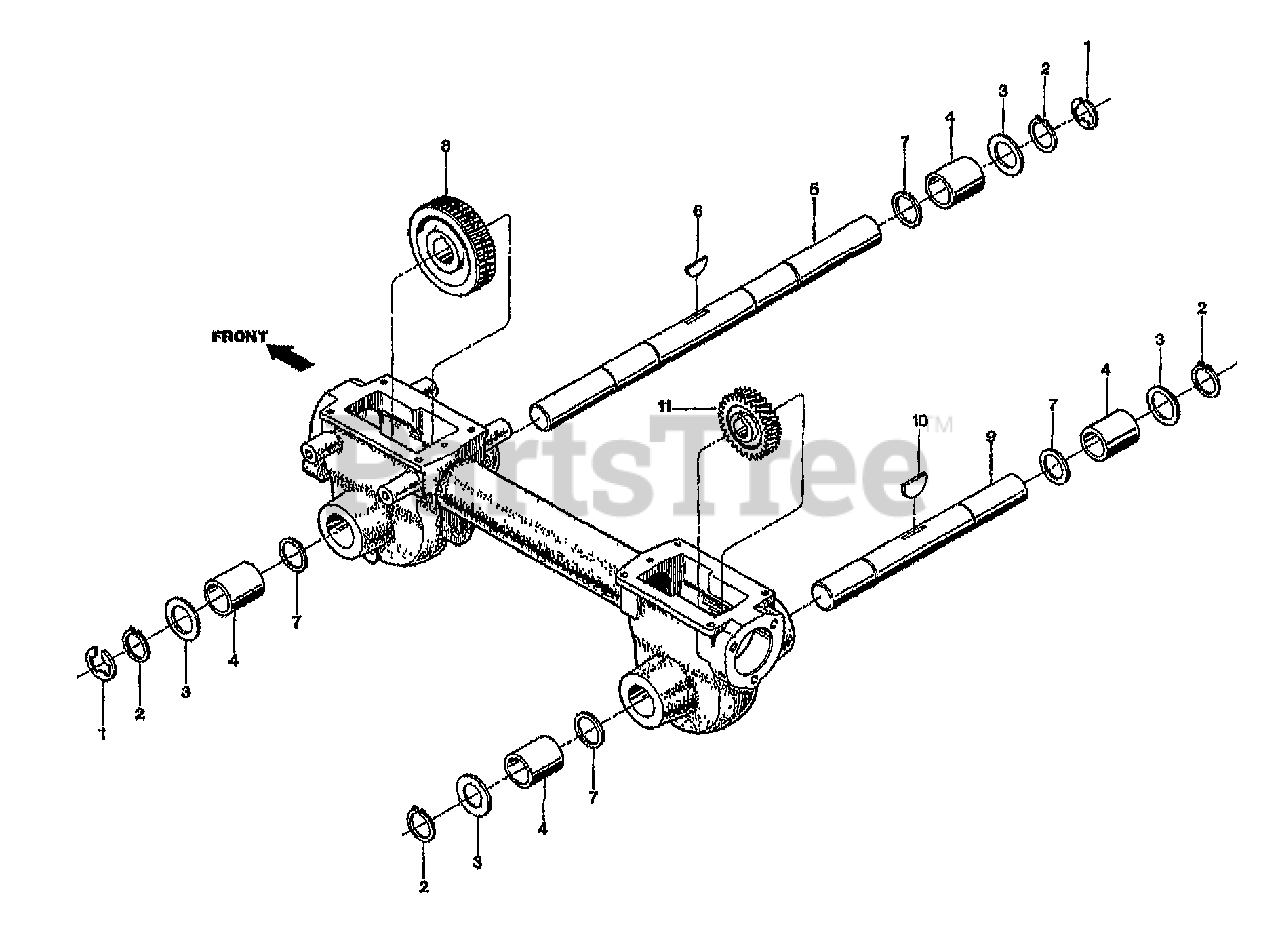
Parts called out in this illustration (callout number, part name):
1	RING-RETAINING 5133-989
2	RING-HEAVY EXT .906 ID
3	SHIM-1.375X1.015X.062
3	SHIM-1.375X1.015X.03
3	SHIM-1.375X1.015X.015
3	SHIM-1.375X1.015X.01
3	SHIM-1.375X1.015X.005
4	BUSHING-1.25X1.005X1.5
5	SHAFT-WHEEL MACH
6	KEY-HI PRO .25X1.062
7	SHIM-1.234X1.015X.062
8	GEAR-WORM 61 TEETH MACH
9	SHAFT-TILLER MACH
9	SHAFT-TUFFY TLR MACH {12155}
10	KEY-WOODRUFF .25X1.12
11	GEAR-WORM BRONZE MACH
11	GEAR-WORM TINE MACH {12155}
